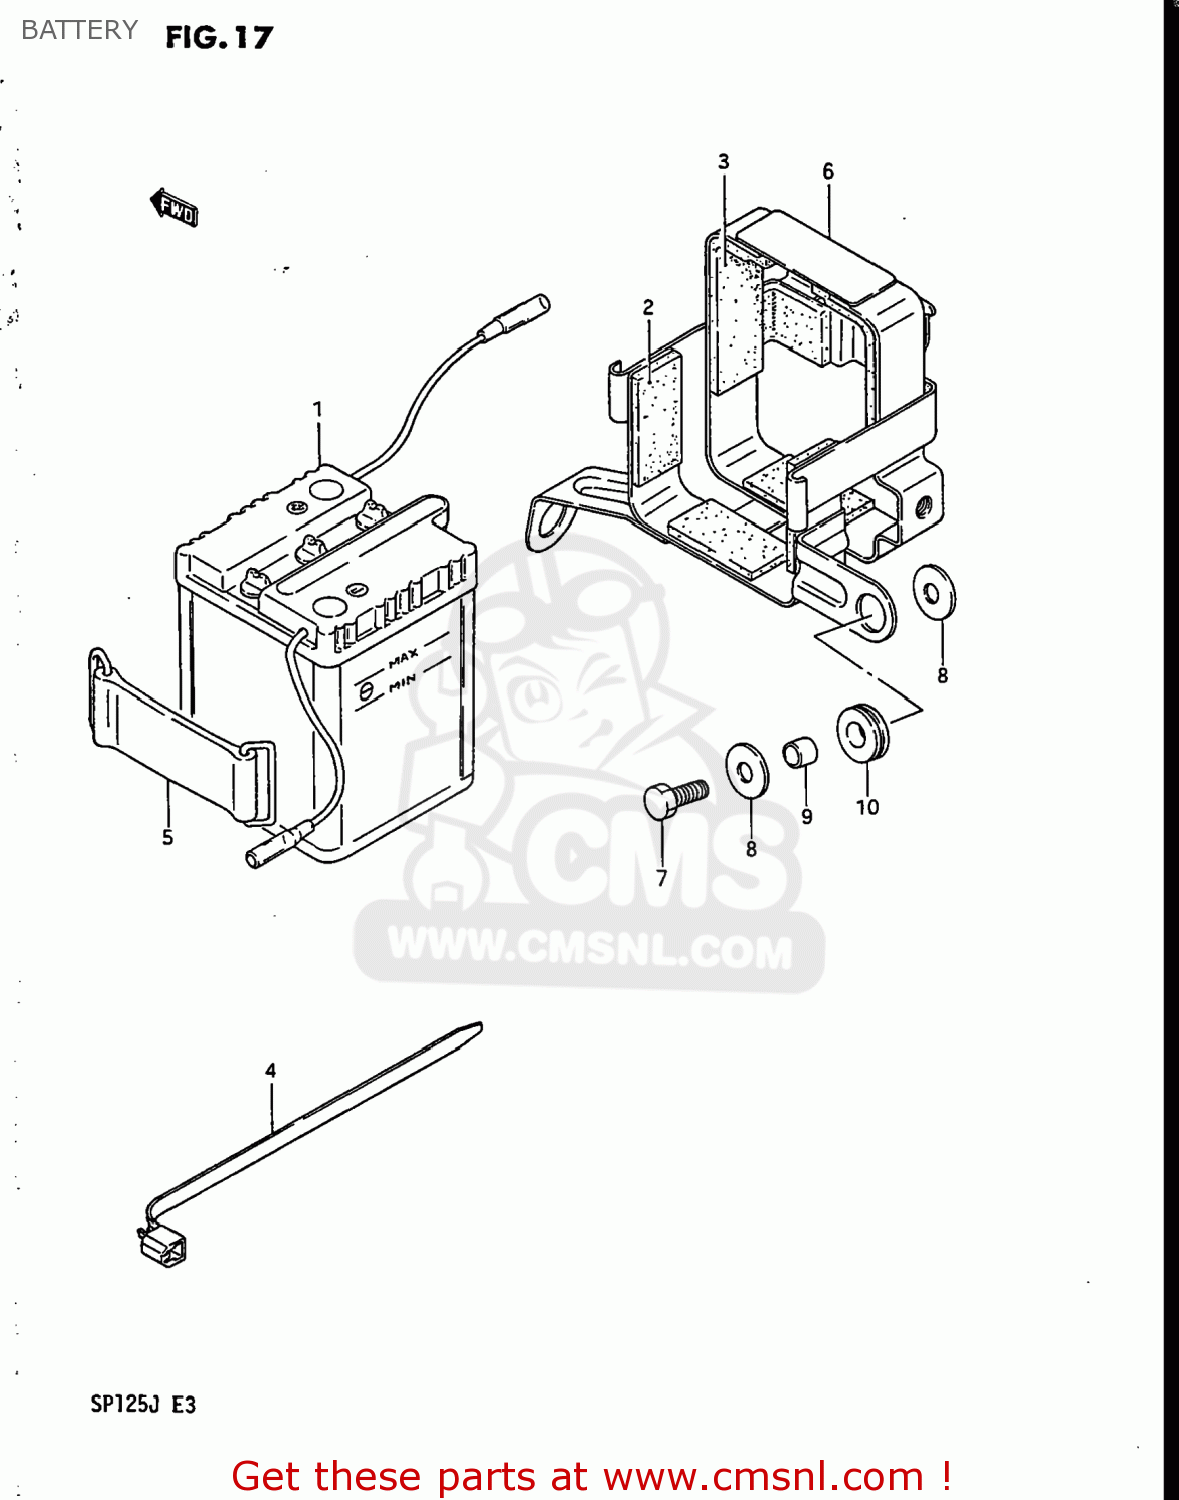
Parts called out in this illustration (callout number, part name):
1	BATTERY ASSY(6N4-2A4.2AH)
2	PROTECTOR,BATTERY
3	PROTECTOR,20X9
4	CLAMP(L:165)
5	BAND
6	HOLDER COMP,BATTERY
7	BOLT
8	WASHER (6.5X20X1.2)
9	SPACER (6X9X5)
10	CUSHION
